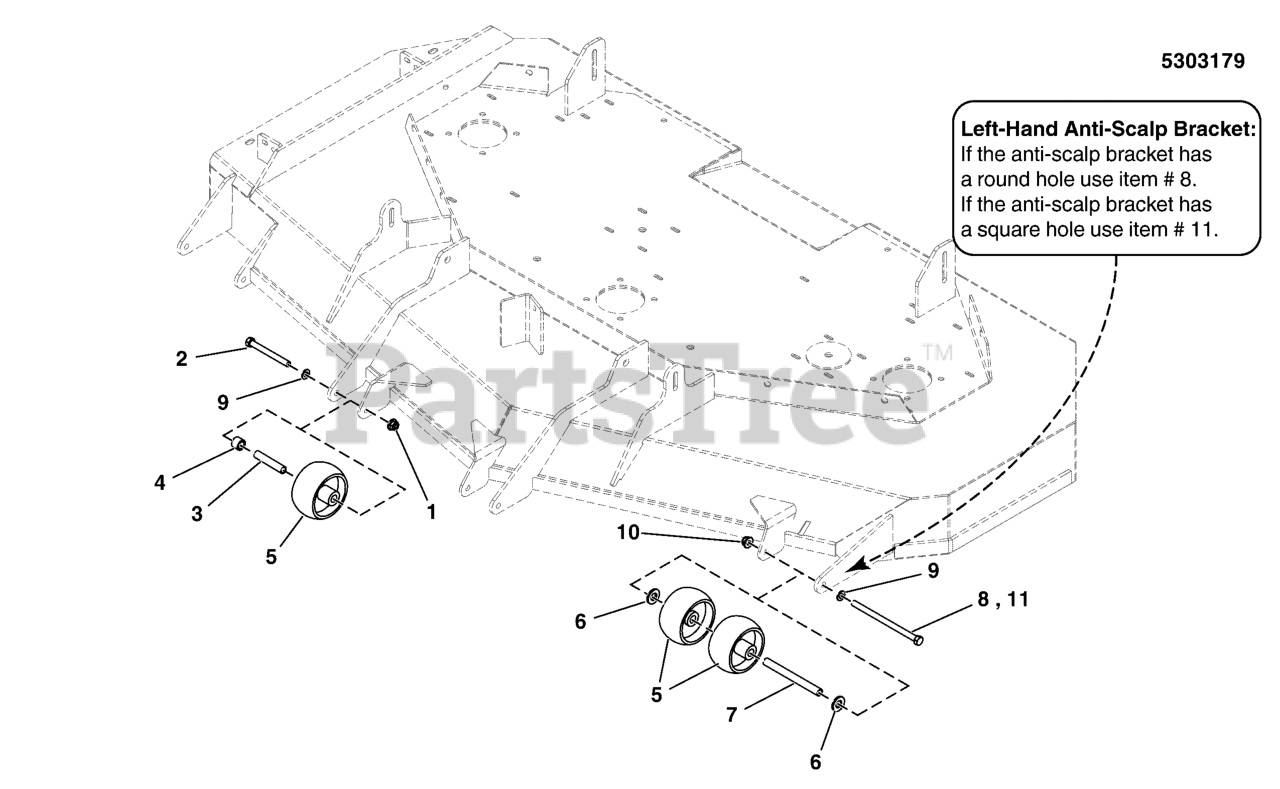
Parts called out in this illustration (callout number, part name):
1	NUT, 3/8 - 16 HEX NYLOCK FLANGE
2	BOLT, 3/8-16 X 3-1/2" GD5 CZ
3	SPACER, .38 X .50 X 2.50, CZ
4	SPACER, .51 X .75 X .56, PM, CZ
5	WHEEL- 2.00 WIDE 3.88 DIA 0.531ID POLY
6	WASHER, 1/2" GD9 YZ
7	SPACER, .38 X .50 X 5.06, CZ
8	BOLT, 3/8-16 X 6" GD5 CZ
9	WASHER, 3/8 SAE
10	NUT, 3/8 - 16 HEX NYLOCK FLANGE
11	BOLT, CARRIAGE, 3/8-16 X 6, GD5, CZ
